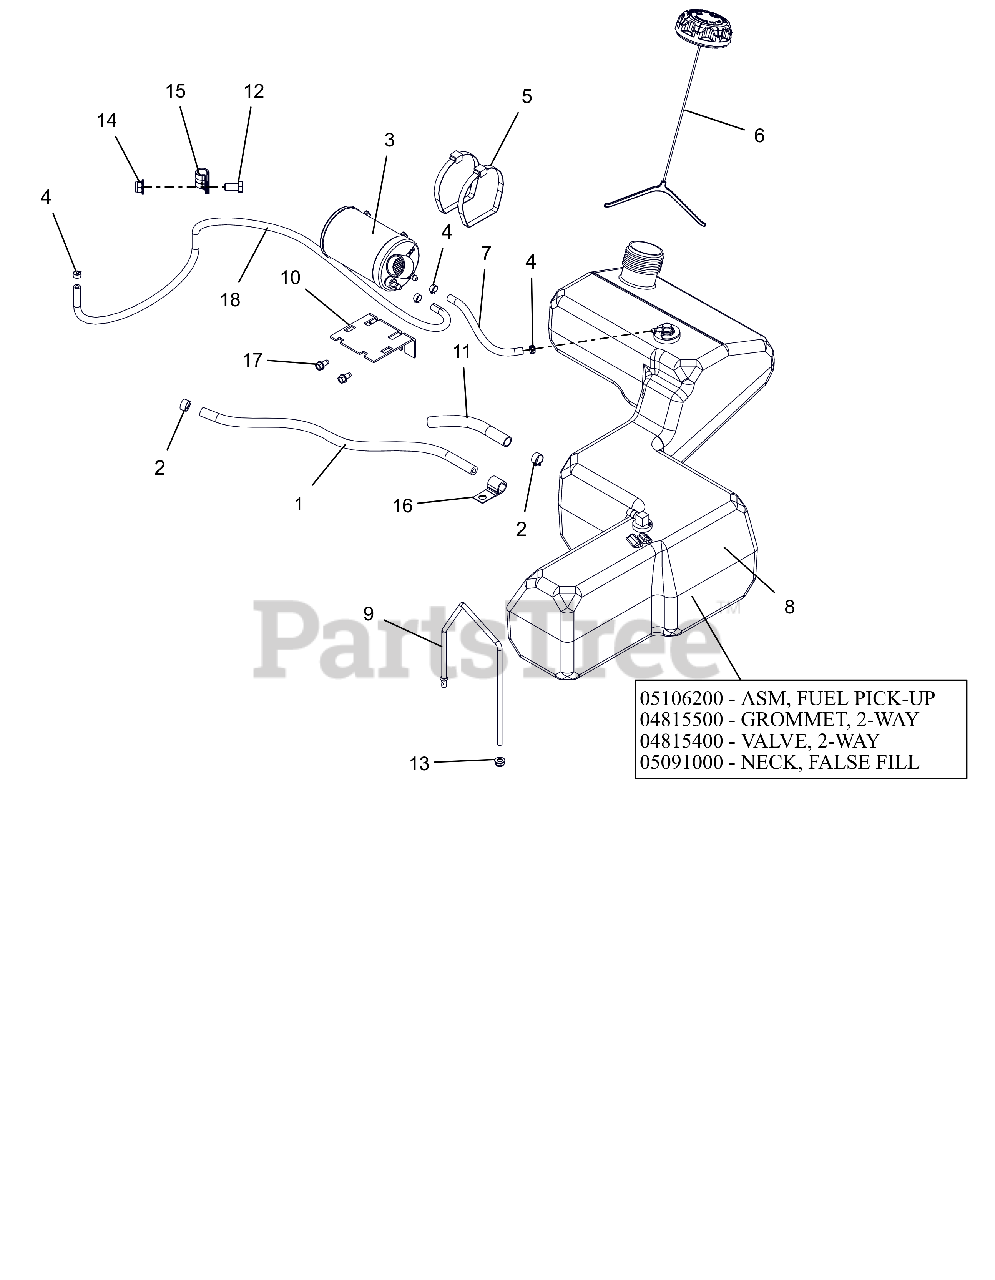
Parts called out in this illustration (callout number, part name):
1	HOSE, .25 LOW-PERM BULK GAS
2	CLAMP, FUEL LINE
3	CARBON CANISTER, 300CC
4	CLAMP-HOSE, SPRING .188
5	P-PLASTIC TIE STRAP LARGE
6	CAP, FUEL VENT-IN 2.25" RATCH.
7	HOSE, .188 30R7 BULK
8	ASSEMBLY, FUEL TANK IKON(2017)
8	ASM, IKON FUEL PICK-UP
8	GROMMET, 2-WAY
8	VALVE, 2-WAY
8	NECK, FALSE FILL-2017 IKON
9	BRKT, FUEL TANK HOLD DOWN
10	BRKT, MOUNT -CARB CANISTER
11	WRAP, ANTIABRASION .5X.064WALL
12	@BLT-HEX .38-16X.75 GR5 YWZC
13	@NUT-LK-NYL-FLG .25-20 YWZC
14	@NUT-LK-NYL-FLG .38-16 YWZC
15	CLAMP, CUSHIONED STEEL
16	J-CLAMP
17	SCR-TAP .25-20X.50 HWH TR YWZ
18	HOSE, .188 30R7 BULK
